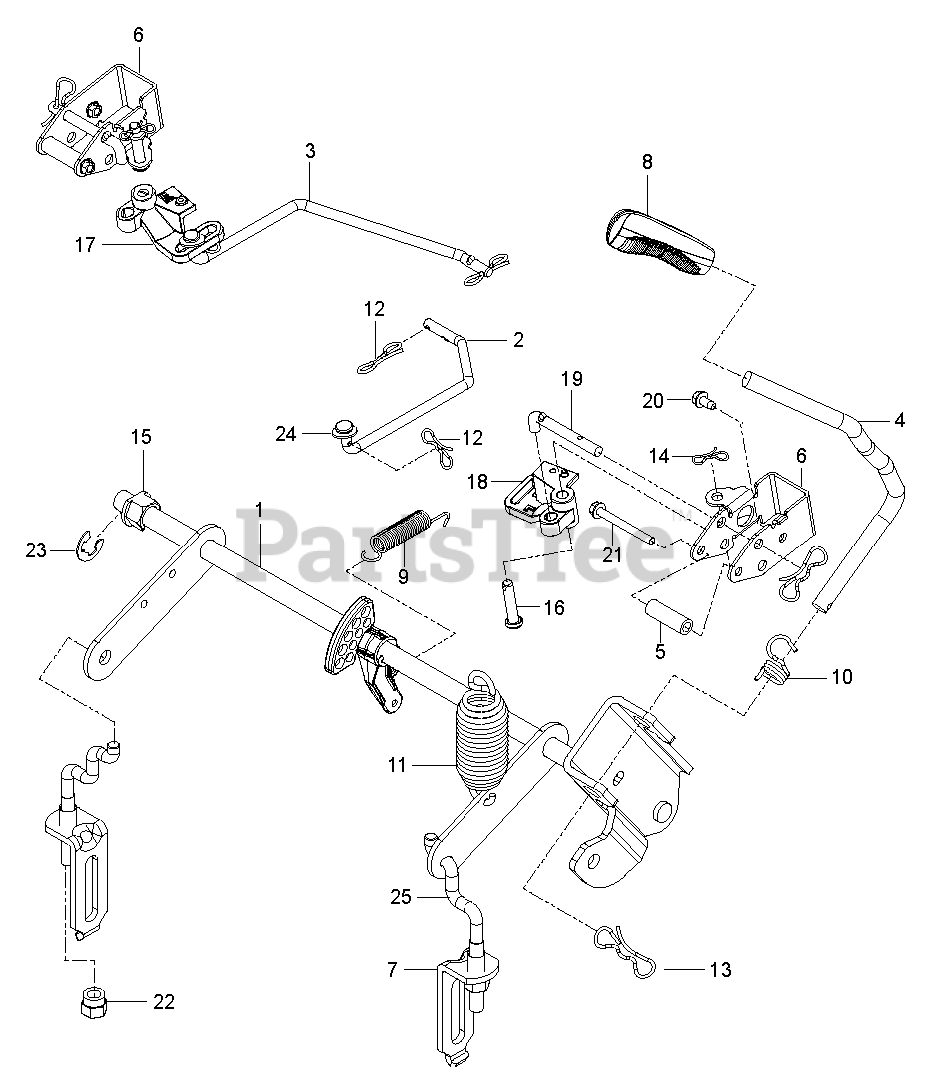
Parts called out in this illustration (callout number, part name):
1	SHAFT ASSY DECK LIFT WELDMENT
2	LINK.BRAKE.PARK.UPPER.LH
3	LINK.BRAKE.PARK.UPPER.RH
4	HANDLE LIFT ZTR
5	SPACER.334.ID.5.OD.1.5.L
6	BRACKET.BELLCRANK.PBRAKE X431
7	ASSEMBLY, BRKT LINK
8	GRIP.HANDLE.LIFT.PVC.BLACK
9	RETURN.BRAKE.PARK.AUTO
10	SPRING.TORSION.LIFT.HANDLE
12	PIN COTTER;LOCKING;BOWTIE;1IN
13	PIN.COTTER.7/16.BOW TI.
14	PIN.COTTER.5/16.BOW TI
15	PLASTIC NUT
16	PIN.5.16X1.5
17	BELLCRANK.RH
18	BELLCRANK.LH
19	ROD.PUSH.BRAKE
20	SCREW.1/4-20X5/8
21	SCREW THD;ROLL;1/4-20 X 2.25
22	NUT, LIFT LINK 7/16-20
23	RETAINING RING LT
24	WASHER
25	LINK, REAR SUSPENSION
